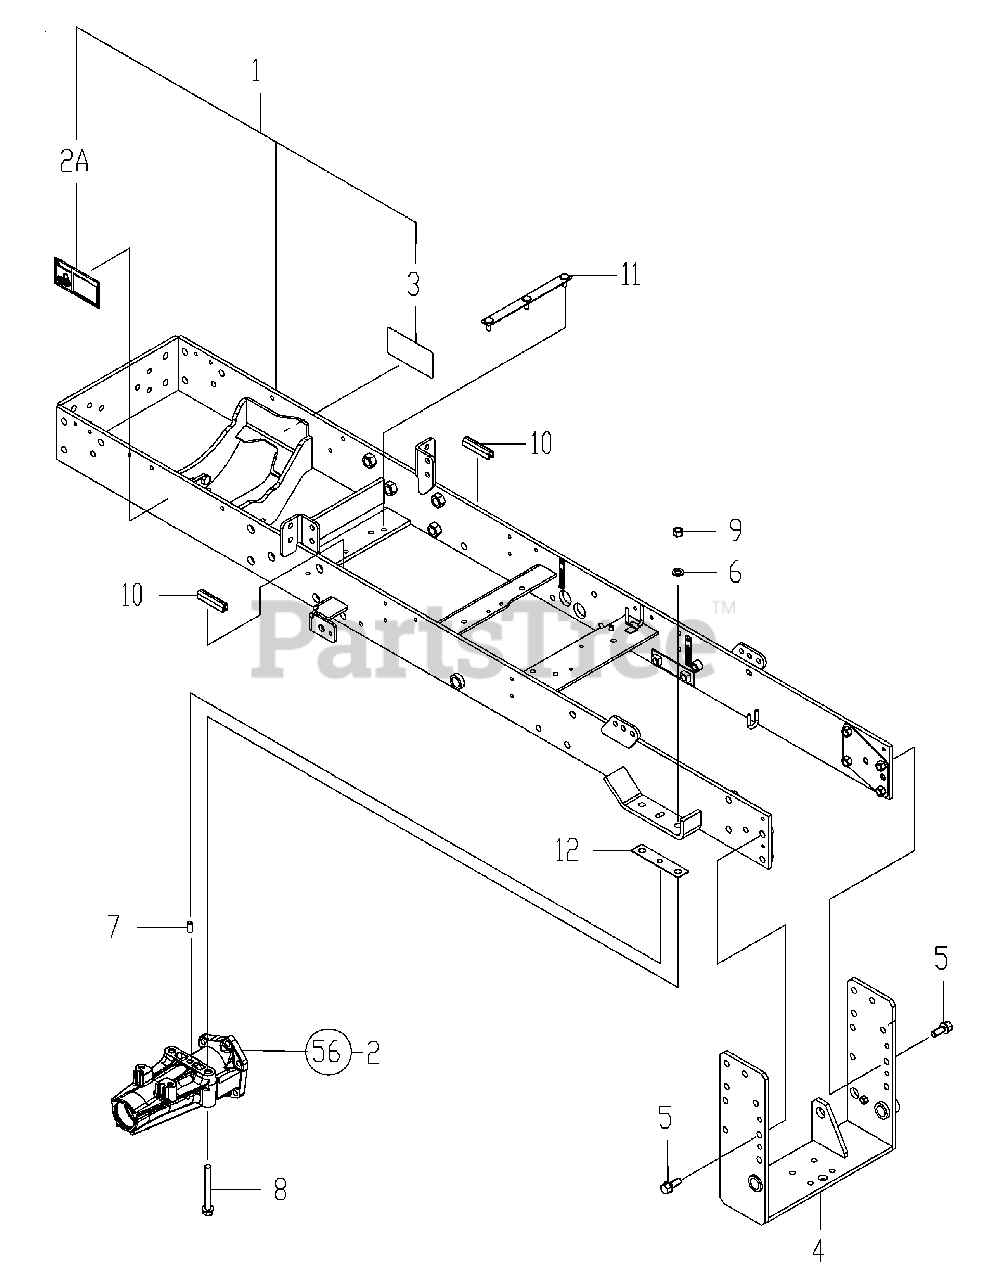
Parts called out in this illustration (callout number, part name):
1	SCT FRAME M ASSY
2A	LABEL, WARNING STOP
3	LABEL,DANGER,START
4	FRAME,LOWER CMP
7	PIN, 10.0A X 20
8	BOLT, 12 X 100
11	PLATE, FUEL TANK COVER
12	SHIM, 1.2
